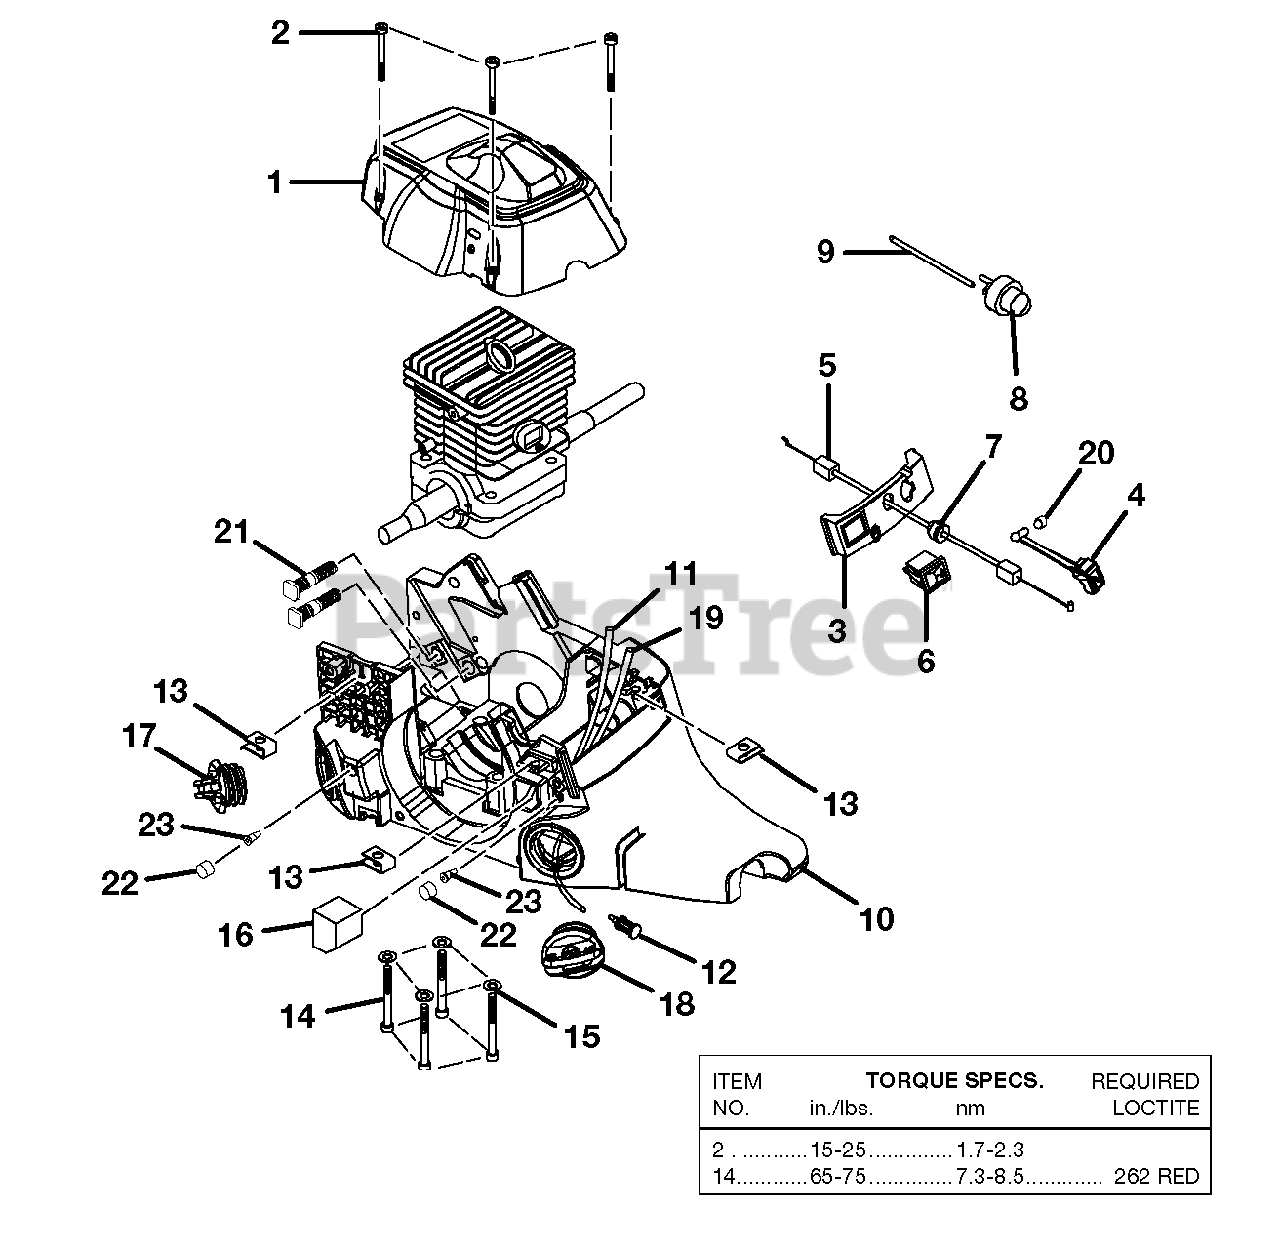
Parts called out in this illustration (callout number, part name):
1	CYLINDER COVER
2	SCREW (10-16 X 1.5 PAN HD.)
3	CONTROL PANEL
4	ROD, CHOKE
5	THROTTLE CABLE
6	SWITCH, ROCKER
7	GROMMET - SPLIT
8	PRIMER BULB
9	RUBBER TUBING (2-1/2 in.)
10	CHASSIS & COMPONENTS ASSEMBLY (45CC)
11	RUBBER TUBING (8-1/2 in.)
12	FUEL FILTER
13	SPEED NUT
14	SCREW (10-24 x 2 in.)
16	PRE FILTER
17	OIL CAP
19	RUBBER TUBING (5-1/2 in.)
20	HAIR PIN, CHOKE ROD
21	BOLT, GUIDE BAR
22	ELEMENT, BRONZE
23	DUCK BILL VALVE
